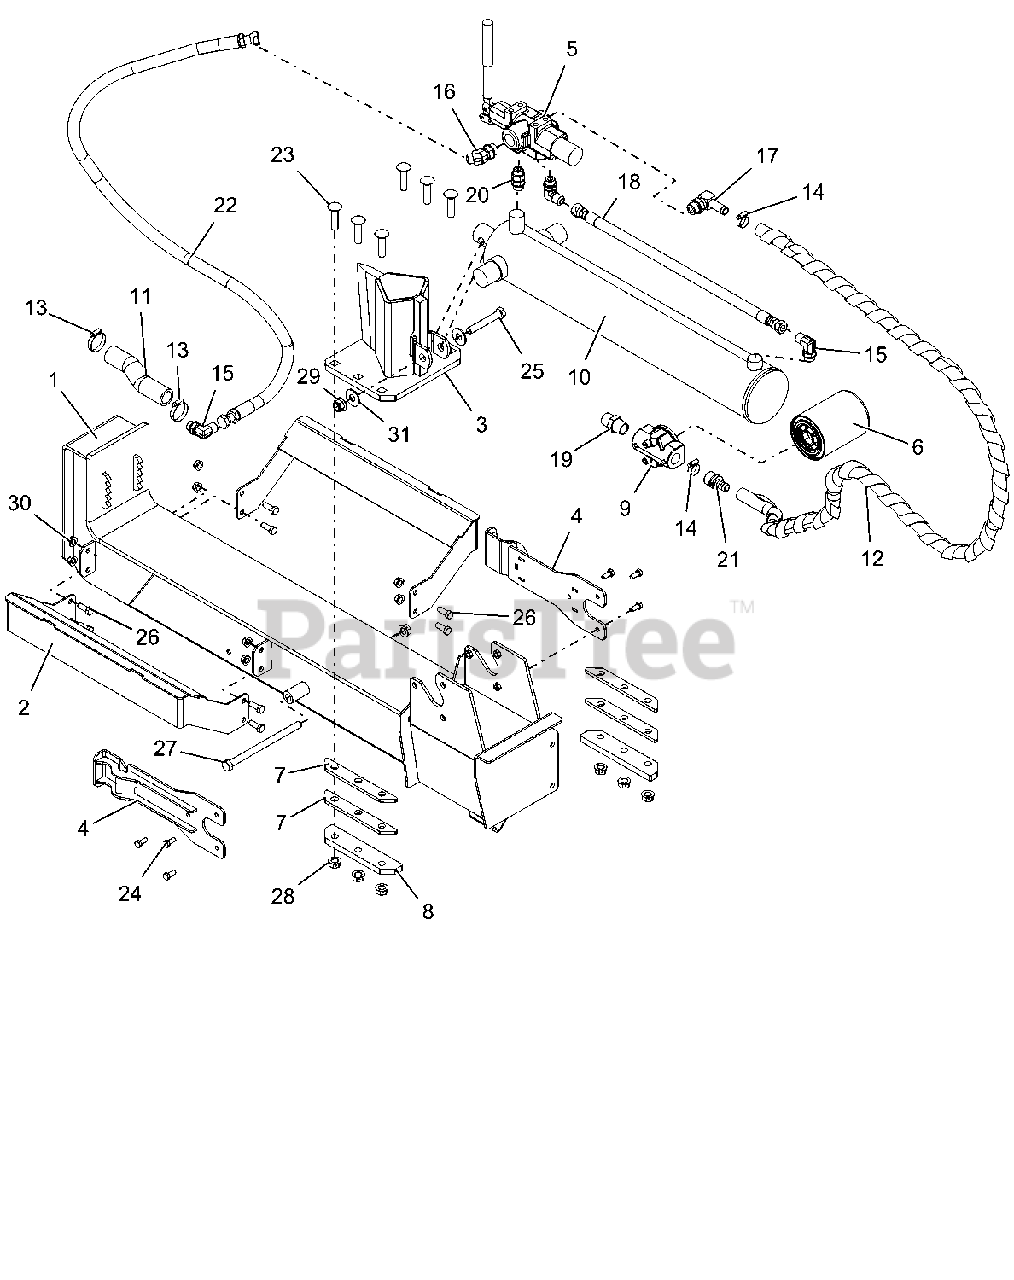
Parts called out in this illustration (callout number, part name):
1	WMT-BEAM-LOG SPLITTER
2	WLDMT, CRADLE, LOG SPLITTER
3	WMT, WEDGE - SPLITTER
4	WLDMT, PLATE - STRIPPER
5	VALVE CONTROL-SPLITTER
6	FILTER,HYDRAULIC OIL-NO BYPASS
7	SPACER, WEDGE
8	RETAINER,WEDGE
9	HEAD,FILTER-3/4 NPT BYPASS
10	CYLINDER, SPLITTER 4.0
11	HOSE, HYD - SUCTION 7.375"
12	HOSE, HYD-RET 801-10 WP 74"
13	CLAMP-HOSE 1.50X.81X1.42
14	CLAMP,.88 DIA. HOSE
15	FTG,HYD 6801-8-8
16	FTG,HYD 6802-8-10
17	FTG,HYD 4601-10-10
18	HOSE, HYD - 22"
19	FTG,HYD 5404-12-12
20	FTG, HYD - STR 08MAORB-08MORB
21	FTG,HYD STRAIGHT 10-12
22	HOSE, HYD - 58"
23	BLT-RDHDSQNKFTH.50-13X2 G8YWZC
24	@BLT-HEX .31-18X.75 GR5 YWZC
25	@BLT-HEX .50-13X3.25 GR5 YWZC
26	@BLT-HEX .38-16X1.00 GR5 YWZC
27	@BLT-HEX .50-13X7.50 GR5 YWZC
28	NUT-LK-CTR-FLG .50-13 YWZC
29	@NUT-LK-NYL-FLG .50-13 YWZC
30	@NUT-LK-TOP-FLG .38-16 YWZC
31	@WSHR-FL-STL.563X1.38X.109YWZC
